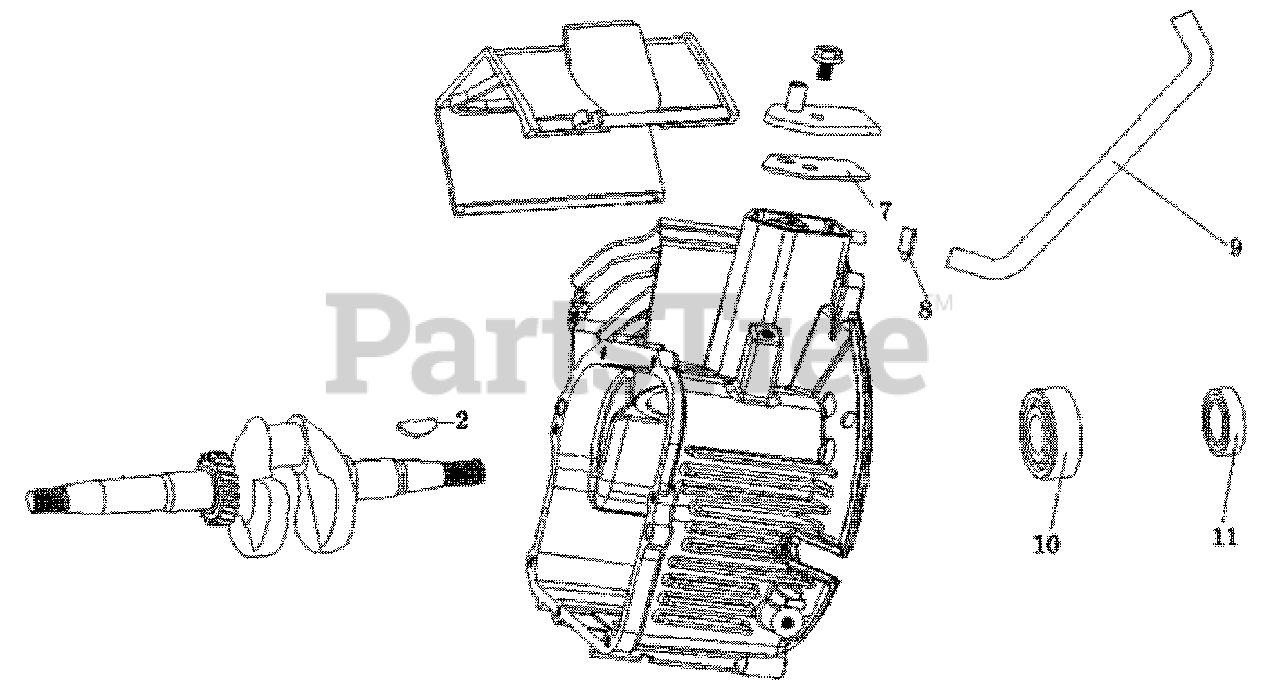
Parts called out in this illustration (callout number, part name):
2	WOODRUFF KEY
7	PACKING,BREATHER CHAMBER
8	LOOP,TUBE
9	TUBE,BREATHER
10	BALL BEARING 6204
11	OIL SEAL D=20_D=35_B=5
